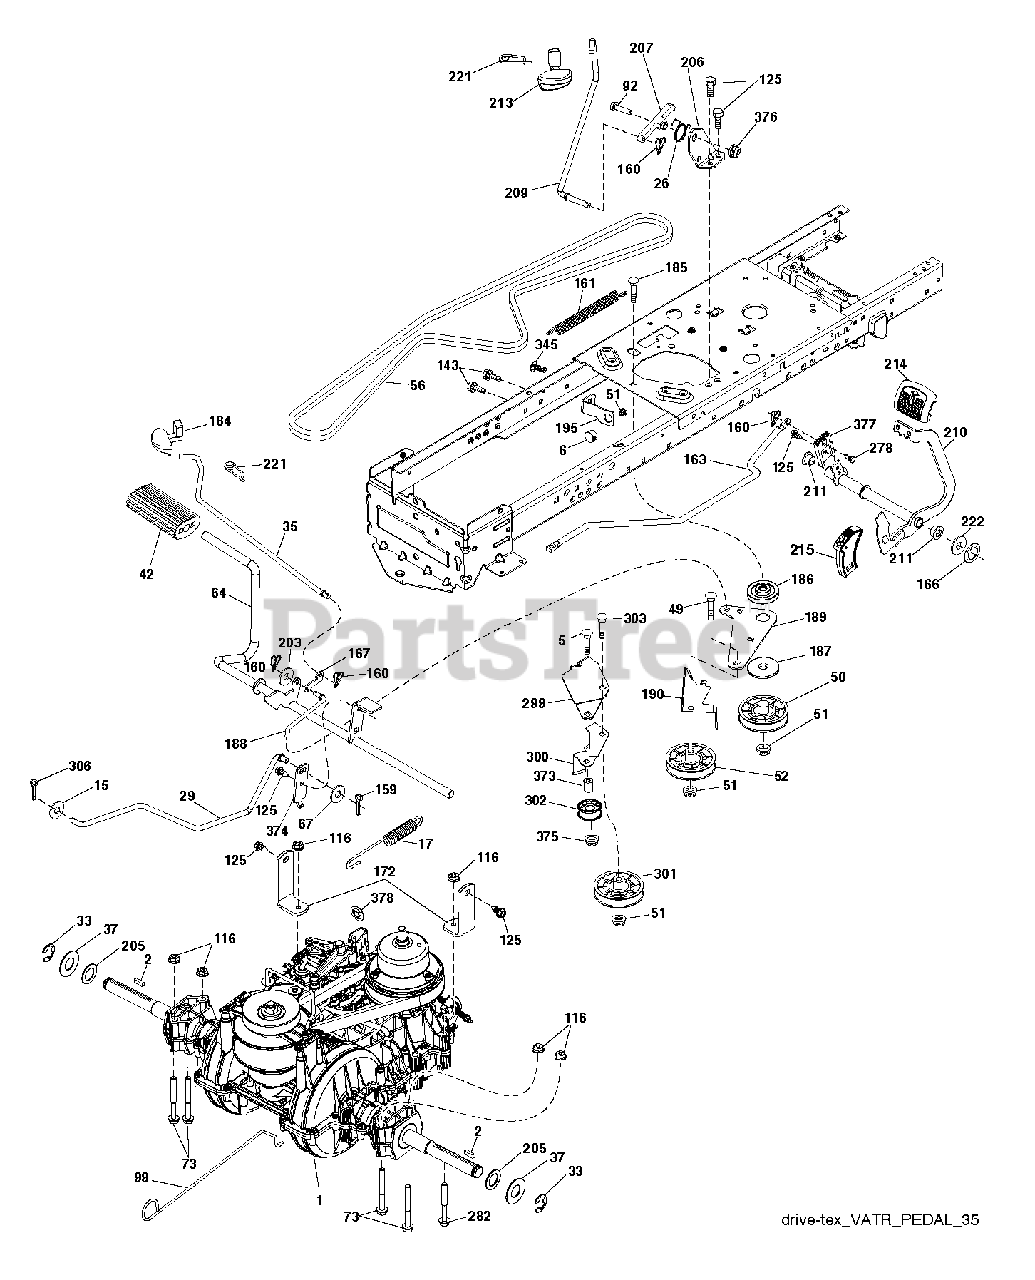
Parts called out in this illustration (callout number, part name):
2	SQUARE KEY
6	BUSHING.SNAP.NYL.BLK.
15	WASHER
17	SPRING.BRAKE.VARIATOR
26	SPRING.RETURN.CRUISE
29	BRAKE.VARIATOR.SD3
35	ROD .BRAKE. PARKING. GT. HUSQ.
37	WASHER.HARDENED
42	PEDAL COVER T
50	IDLER.FLAT.910.OFFSET
51	NUT LOCK FLG 3/8-16 UNC
52	IDLER.V-GROOVE.910.OFFSET
56	BELT.DRIVE.MOWER.TEX.42"
64	SUBASM.SHAFT.PEDAL.BRAKE
67	WASHER
73	BOLT HEX 5/16-18 GR 5
92	BOLT
99	ROD.BYPASS.VARIATOR.GEN2
116	NUT LOCK HEX FLANGE 5/16-18
125	SCREW
143	SCREW LT
159	COTTER PIN
160	RETAINER CLIP
161	SPRING, RETURN LT
163	ROD.CONTROL.PEDAL.VARIATOR
166	NUT.PUSH.625
167	LATCH.BRAKE.SPRING
172	STRAP.TORQUE.VARIATOR
184	HANDLE.PARKING.BRAKE.H (BLK)
186	SPACER.RETAINER
187	WASHER 12/32X2X10GA
188	RP LINK.CLUTCH.GROUND.DRIVE
189	BELLCRANK.GROUND.DRIVE.TEX.
190	KEEPER.BELLCRANK.DRIVE
195	BRACKET.BRAKE.BRAKE.VAR.SD
203	WASHER
206	BRACKET.MOUNT.CRUISE.LATCH
207	LATCH.CONTROL.CRUISE.VARIATOR
209	ROD.CONTROL.CRUISE.GT.
210	WELDMENT.PEDAL.VARIATOR
211	BEARING.NYLON
213	KNOB.CONTROL.CRUSIE.HU
214	PEDAL.FORWARD.PAD.TEX
215	CAP.PEDAL.REVERSE.VARIATOR
221	RETAINER.SPRING.CLIP.H
222	WASHER 21/32 X 1-1/4 X 10 GA.
278	BOLT CRUISE VARIATOR
282	BOLT HEX FLGHD 5/16-18X3 GR. 5
299	BRACKET.MOUNT.IDLERS
300	KEEPER.IDLERS.REAR.VARIATOR
301	PULLEY.IDLER.V-GROOVE
302	PULLEY.IDLER.FLAT.2"
303	BOLT CARRIAGE
306	PIN COTTER
345	BOLT
373	SPACER.IDLER
374	ARM.CONTROL.BRAKE
376	NUT.FLANGE.HEX.5/16X18.BLACK
377	GEAR.SECTOR.CONTROL.CRUISE.VAR
378	NUT.PUSH.8MM
